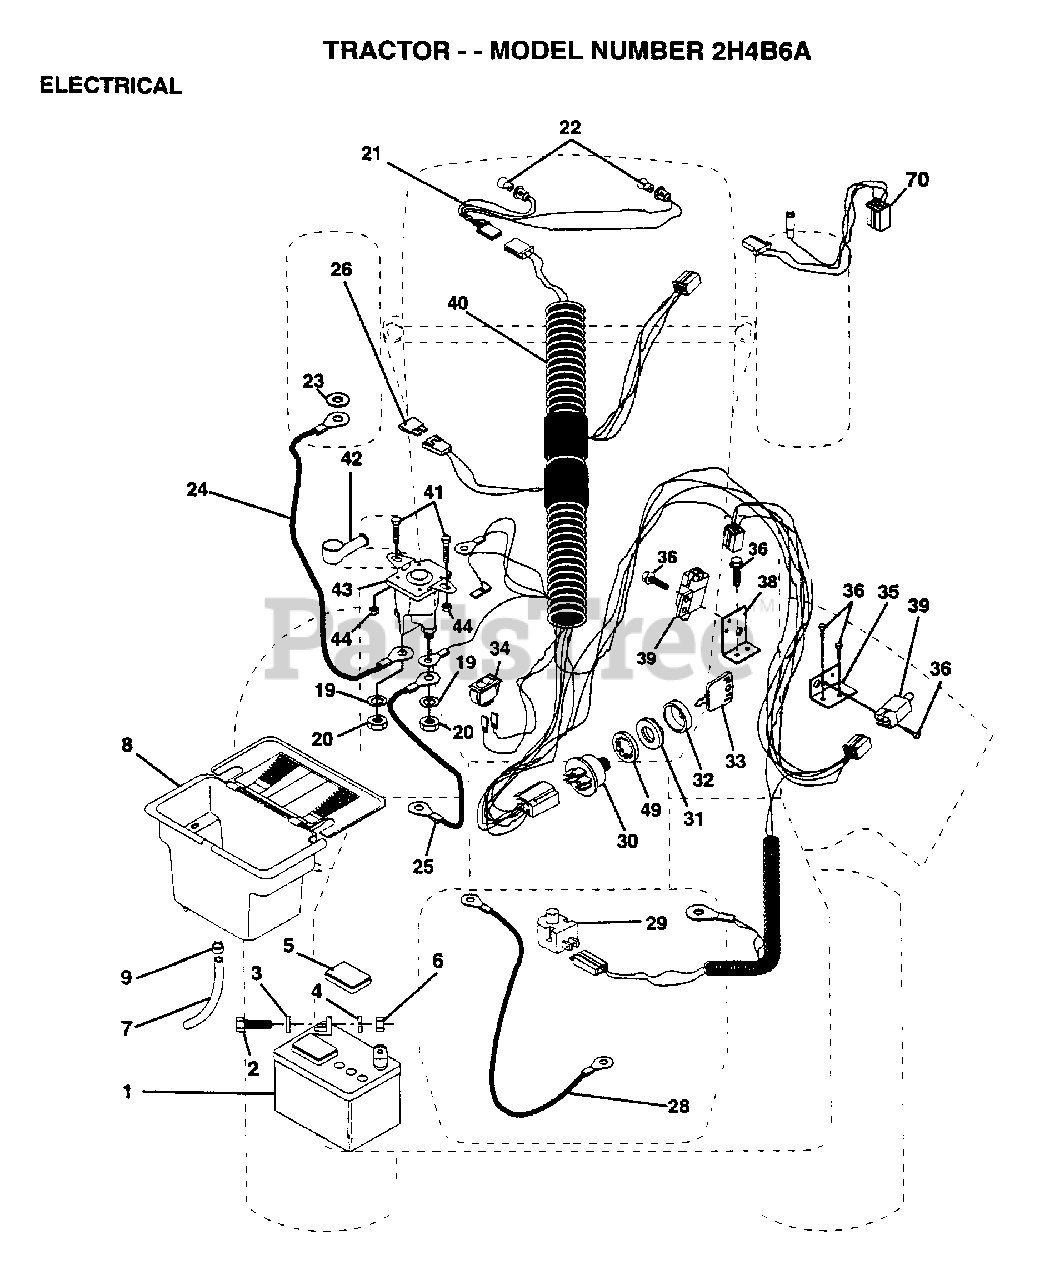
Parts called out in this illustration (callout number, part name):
2	BOLT LT
3	WASHER
4	LOCKWASHER
5	"CAP,BATTERY "
7	TUBE T
9	HOSE CLAMP T
20	NUT
21	"HARNESS,LIGHT SOC"
22	HEADLAMP BULB
23	LOCKWASHER
24	"CABLE T, BATTERY"
26	FUSE HYT
28	CABLE T
29	SWITCH SEAT
32	COVER KEY SWITCH
33	KEY MLD GEN DELTA
34	SWITCH LT
35	BRACKET LT
36	SCREW
38	BRACKET SWITCH IN
39	SWITCH INTERLOCKT
40	HARNESS IGN DASH
41	BOLT HXHD FIN
44	NUT HXKEP 1/4X20
49	LOCKWASHER
70	HARNESS ENG DUAL
